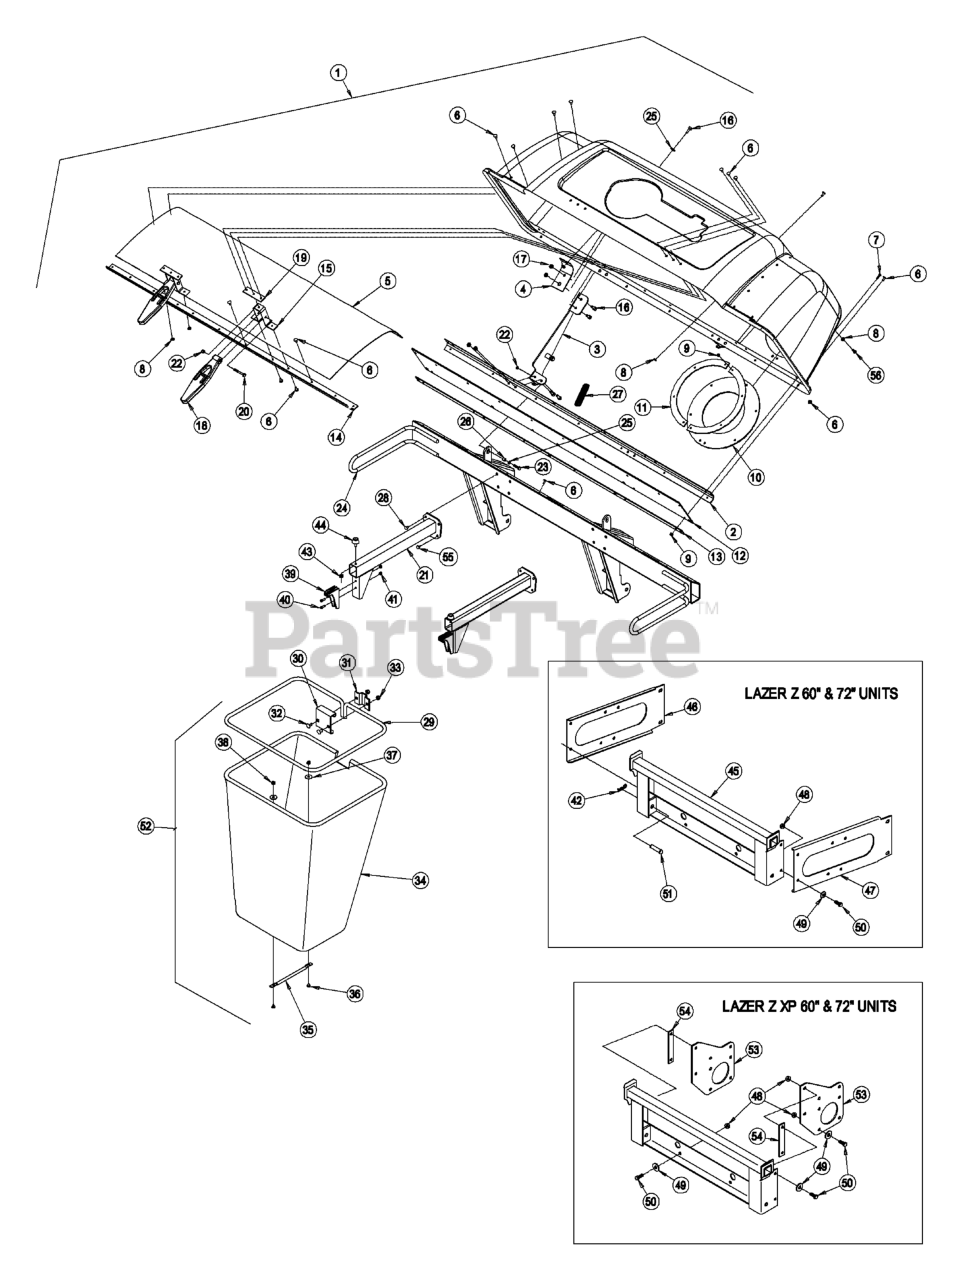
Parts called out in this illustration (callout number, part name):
1	ASM, HOOD
2	STIFFENER-BAGGER, TOP
3	HINGE ASM
4	REINFORCEMENT-HOOD, BAGGE
5	SCREEN-BAGGER
6	RIVET-BLIND
7	SCREW-HEAD, TRUSS
8	WASHER-FLAT
9	NUT-LOCK, NI
10	SEAL-TUBE
11	CLAMP-SEAL
12	SEAL-HINGE
13	PLATE-BACKING
14	SUPPORT-SCREEN
15	BRACKET-MOUNT
16	SCREW-HH
19	PLATE-LATCH, REINFORCEMEN
20	SCREW-HH
22	NUT-LOCK, NI
23	SCREW-HH
25	WASHER-FLAT
27	SPRING-EXTENSION
28	SCREW-HH
29	FRAME-BAG
30	HANGER-BAG
32	BOLT-CARR
33	NUT-LOCK, NI
35	HANDLE-BAG
36	BOLT-CARR
38	NUT-LOCK, NI
40	SCREW-PPH
42	PIN-COTTER
45	MOUNT-BAGGER
47	BRACKET-FRAME, RH
48	NUT-HHF, WHIZ
49	WASHER-BELLEVILLE
50	SCREW-HH
51	PIN-CLEVIS
53	PLATE-MOUNT, BAGGER
55	SCREW-HSBH
56	SCREW-PPH
